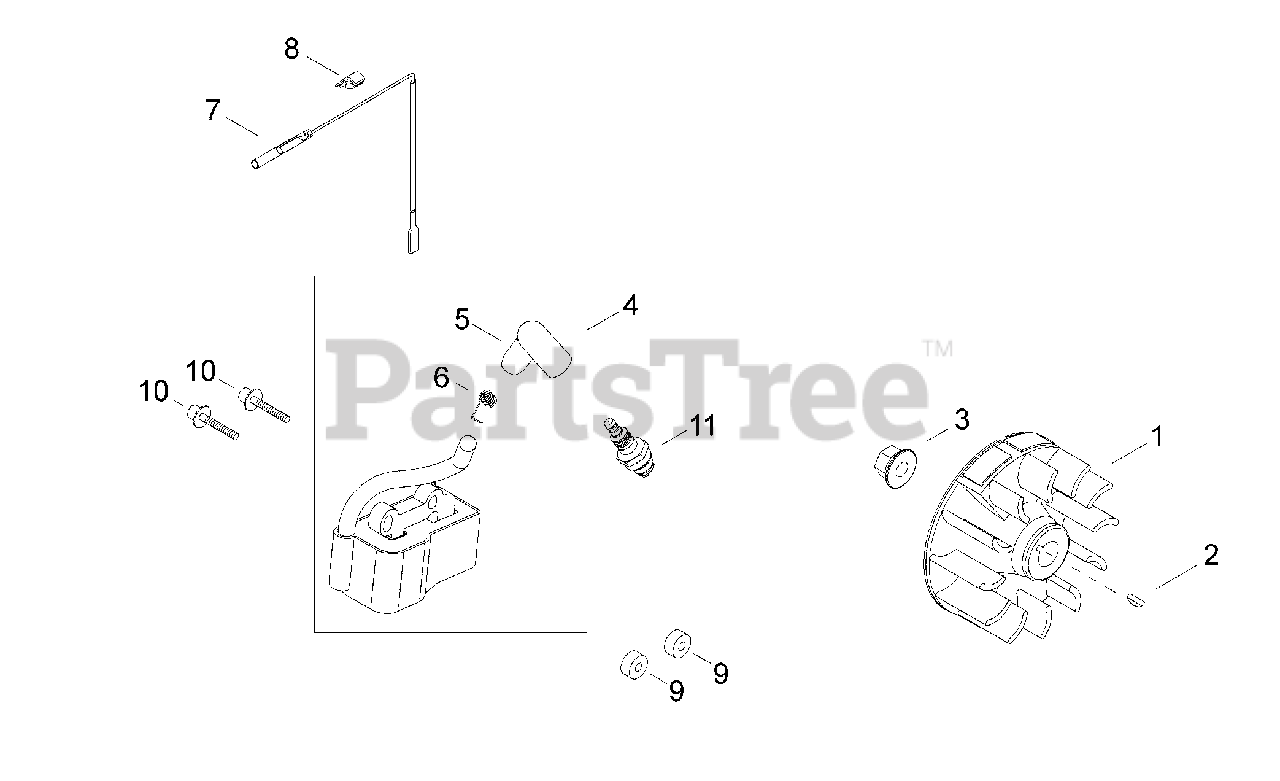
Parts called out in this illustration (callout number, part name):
1	FLYWHEEL
2	KEY - 3X10
3	NUT - 8
4	IGNITION COIL ASSY
5	CAP, SPARK PLUG
6	TERMINAL, SPARK PLUG CAP
7	LEAD - IGNITION
8	GROMMET
9	INSULATOR
10	SCREW - 4X26
11	SPARK PLUG -- CMR-5H
